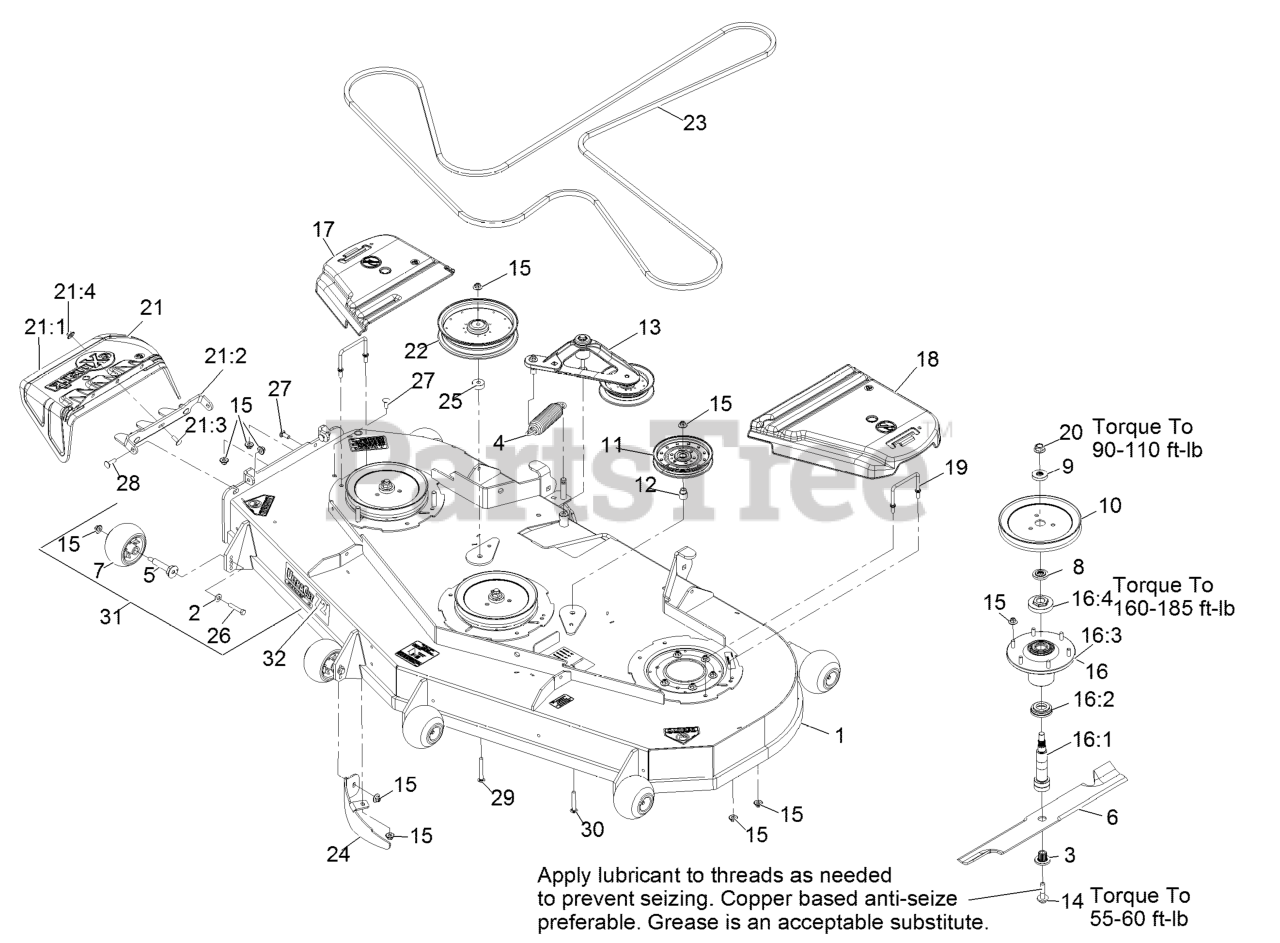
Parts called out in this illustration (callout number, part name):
1	DECK W/ DECALS ASM-72
2	WASHER-BELLEVILLE
3	BUSHING,SPLINED
4	SPRING-EXTENSION
7	ROLLER-SCALP, ANTI
8	SPACER,SPLINED STEPPED
9	SPACER,SPLINED
10	SHEAVE,BLADE DRIVE 9.00
12	BUSHING-IDLER
13	DECK IDLER ASM
14	SCREW,SEMS 1/2-20 X 2.19
15	Nut-Nyloc 3/8-16 Flg
16	ASM,SPINDLE HOUSING
16:1	GUARD,BOTTOM
16:2	ASM,CUTTER HOUSING
16:3	NUT, SPINDLE 7/8-14
16:4	SPINDLE,DOUBLE SPLINE
17	COVER-BELT, RH
18	COVER-BELT, LH
19	WIREFORM-COVER
20	NUT-FLANGE, CENTERLOCK
21	ASM,DISCHARGE CHUTE
21:1	CHUTE,DISCHARGE
21:2	BRACKET,DISCHARGE CHUTE
21:3	SCREW-CARR
21:4	Nut-Nyloc 3/8-16 Flg
22	PULLEY-IDLER
23	BELT-V
24	BAFFLE-DOGLEG, LZ72
25	SPACER-IDLER
26	SCREW-HH
27	SCREW-CARR
28	Bolt-Carriage 3/8-16 X 1 1/4
29	SCREW-CARR
30	SCREW-CARR
32	DECAL,ULTRACUT 72 SERIES
